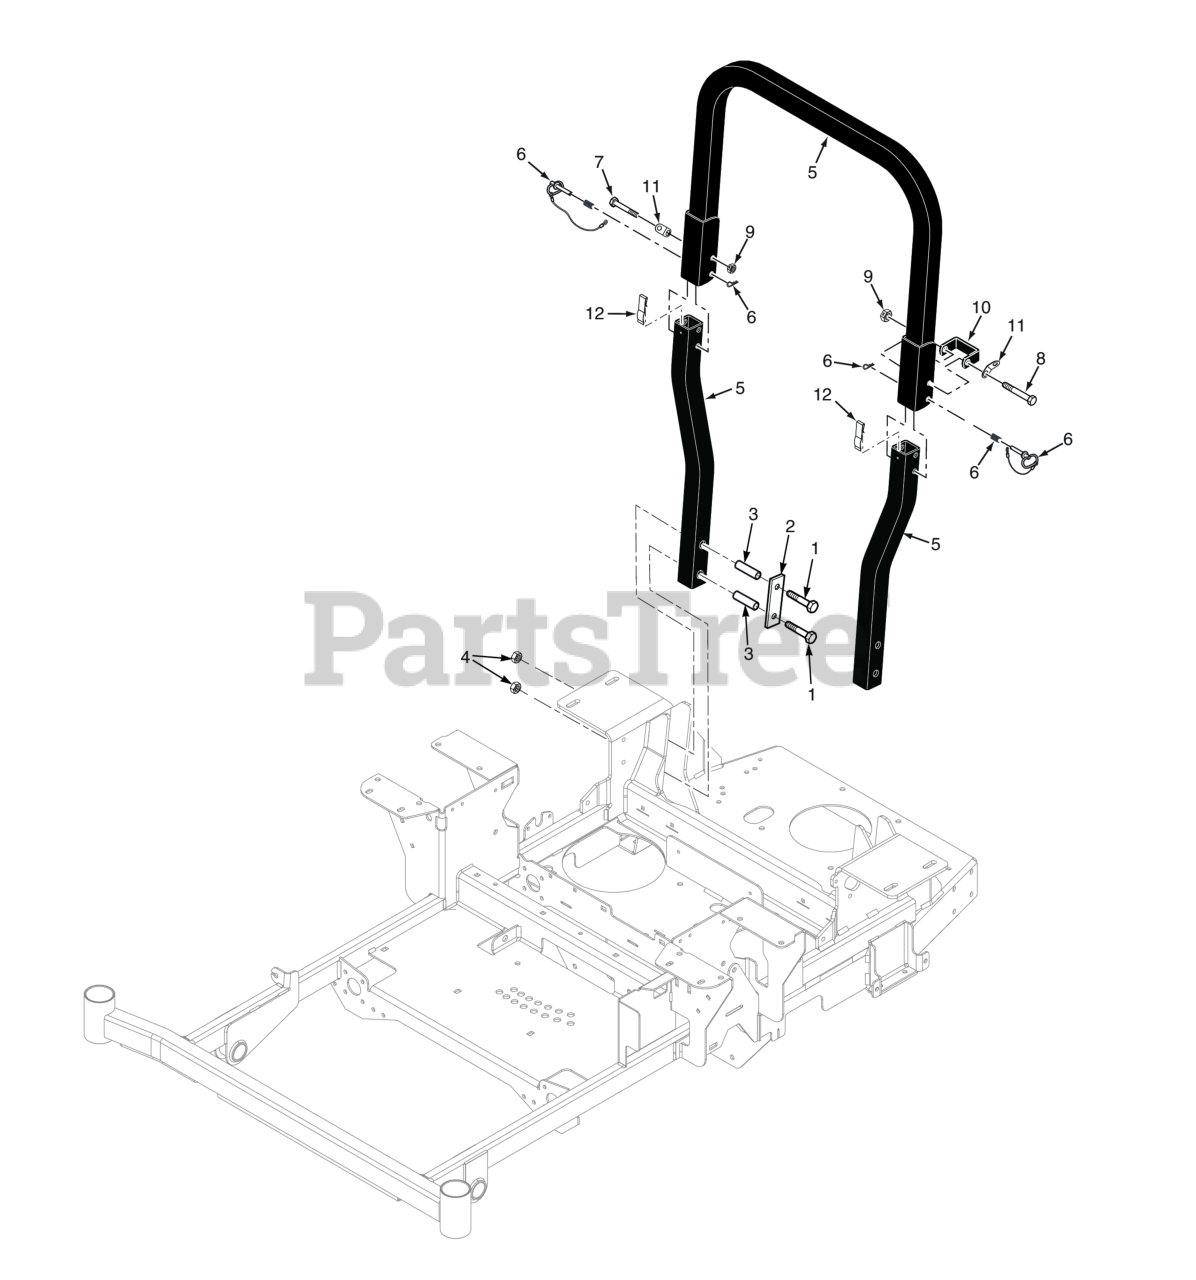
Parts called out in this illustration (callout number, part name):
1	Bolt, Hex Head 1/213 x 3" Gr. 8
2	ROPS Mounting Plate
3	Bushing, SFZ ROPS
4	Nut, Elastic Stop 1/2-13, (STT-52 & STTII-52)
5	ROPS, (Scag Gold)
6	Pin Assembly, ROPS Hinge
7	Bolt, Hex Head, 1/2-13 x 3-1/4"
8	Bolt, Hex Head 1/2-13 x 3-1/2"
9	Locknut, Hex 1/2-13 Center Lock
10	Stop, ROPS
11	Clip, ROPS
12	Spring, ROPS Anti-Rattle
